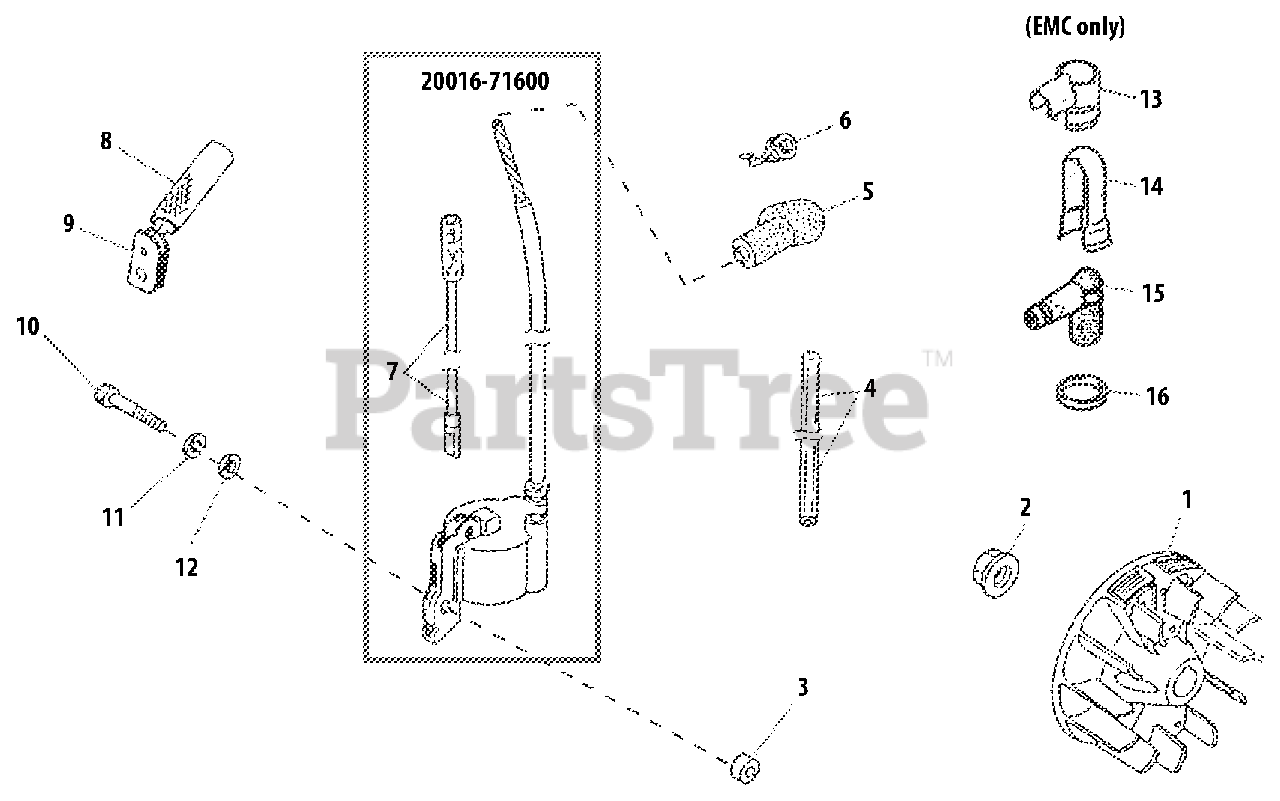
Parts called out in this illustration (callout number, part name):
1	FLYWHEEL
2	NUT - 8
3	INSULATOR
4	TUBE
5	CAP, SPARK PLUG
6	TERMINAL, SPARK PLUG CAP
7	LEAD - IGNITION
8	TUBE
9	GROMMET
10	SCREW - 4X26
11	LOCKWASHER - 4
12	WASHER - 4
13	CAP, SPARK PLUG
14	SHIELD
15	CAP, SPARK PLUG
16	SEAL, DUST
20016-71600	IGNITION COIL ASSY
